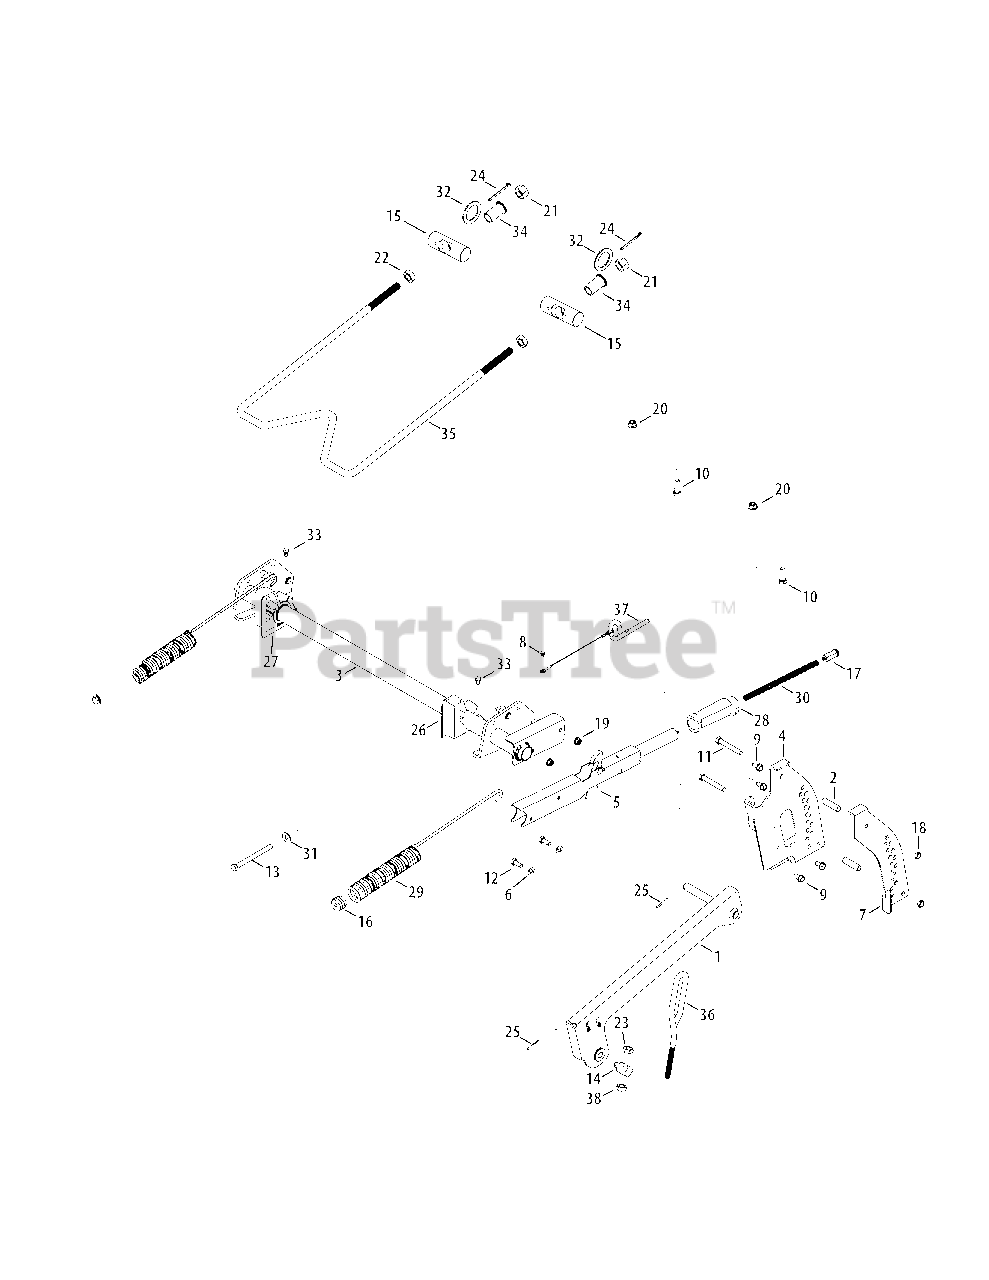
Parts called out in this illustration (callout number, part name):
1	Lift Arm, RH
1	Lift Arm, LH
2	Spacer, .386 x .63 x 1.75
3	Deck Lift Shift Assembly
4	Index Bracket Assembly
5	Latch Handle Assembly
6	Flat Washer .330 ID x .630 OD
7	Outer Index Bracket
8	Screw, #10-16, .50
9	Hex Washer Screw, 5/16-18 x .750
10	Hex Screw, 3/8-16 x 1.00
11	Hex Head Screw, 3/8-16 x 2.50
12	Hex Cap Screw, 5/16-18 x .75
13	Hex Screw, 3/8-16 x 4.25
14	Ferrule, .496 x .528
15	Pivot Pin, 1.25
16	Spring Insert
17	Handle Button
18	Jam Lock Nut, 3/8-16
19	Flange Lock Nut, 5/16-18
20	Flange Lock Nut, 3/8-16
21	Nylock Nut, 5/8-11
22	Jam Nut, 5/8-11
23	Nut, Jam, 1/2-13
24	Cotter Pin, 3/16 x 2.0
25	Cotter Pin 1/8 x 1.25
26	Deck Lift Bracket
27	Deck Lift Bracket, LH
28	Grip, Deck Lift Handle
29	Extension Spring, 1.485 OD x 17.58
30	Spring, Compression, .4 x 8.52
31	Flat Washer, .385 x .870 x .092
32	Flat Washer, 1.875 x 1.38 x .097
33	Shoulder Screw, .500 x 1/4-20
34	Flange Bearing, .875 x .702 x 1.10
35	Deck hanger Rod, 5/8
36	Lift Adjust Link
37	Lock Rod, .375
38	Hex Nut, 1/2-13
